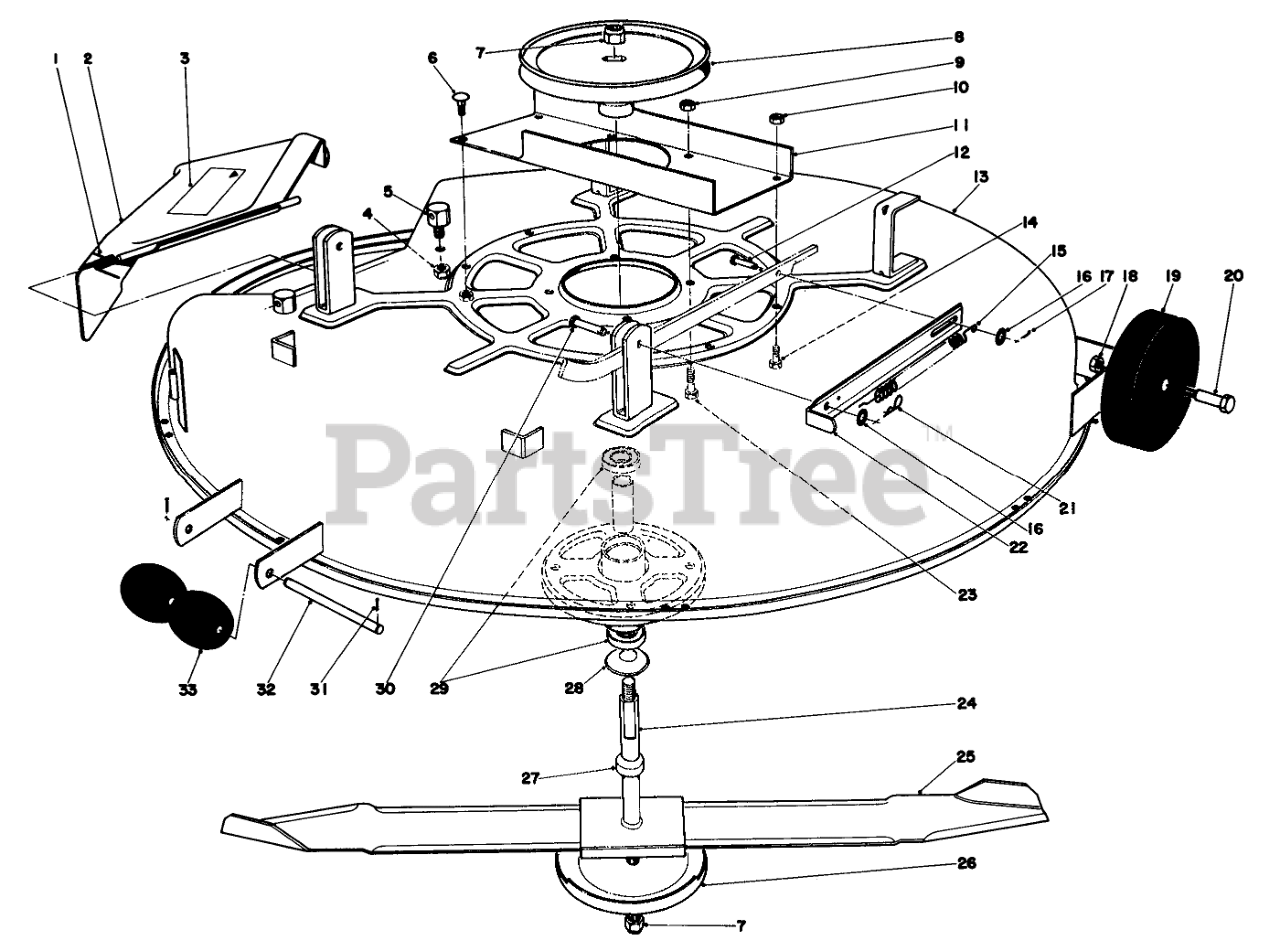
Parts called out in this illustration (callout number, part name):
1	SPRING
2	Deflector Assembly (Incl. Ref. #3)
3	Decal
4	NUT-LOCK, SIDE
5	POST-PIVOT
6	SCREW-CARR
8	PULLEY(BLADE DRIVE)
9	NUT-LOCK, CONE
11	REINFORCEMENT CHANNEL
12	PIN-CLEVIS
13	Cutter Deck
14	SCREW-HH
15	DECK TENSION SPRNG O
16	WASHER-FLAT
17	PIN-COTTER
18	Nut
19	DECK WHEEL
21	PIN-COTTER
22	DECK SPRING STRAP R
23	SCREW-HH
24	Spindle Assembly (Incl. Ref. #27-29)
25	Blade
26	Cup
27	SPACER
28	DUST COVER
29	BEARING
30	PIN-CLEVIS
31	PIN-COTTER
32	ROLLER SHAFT
33	ROLLER
